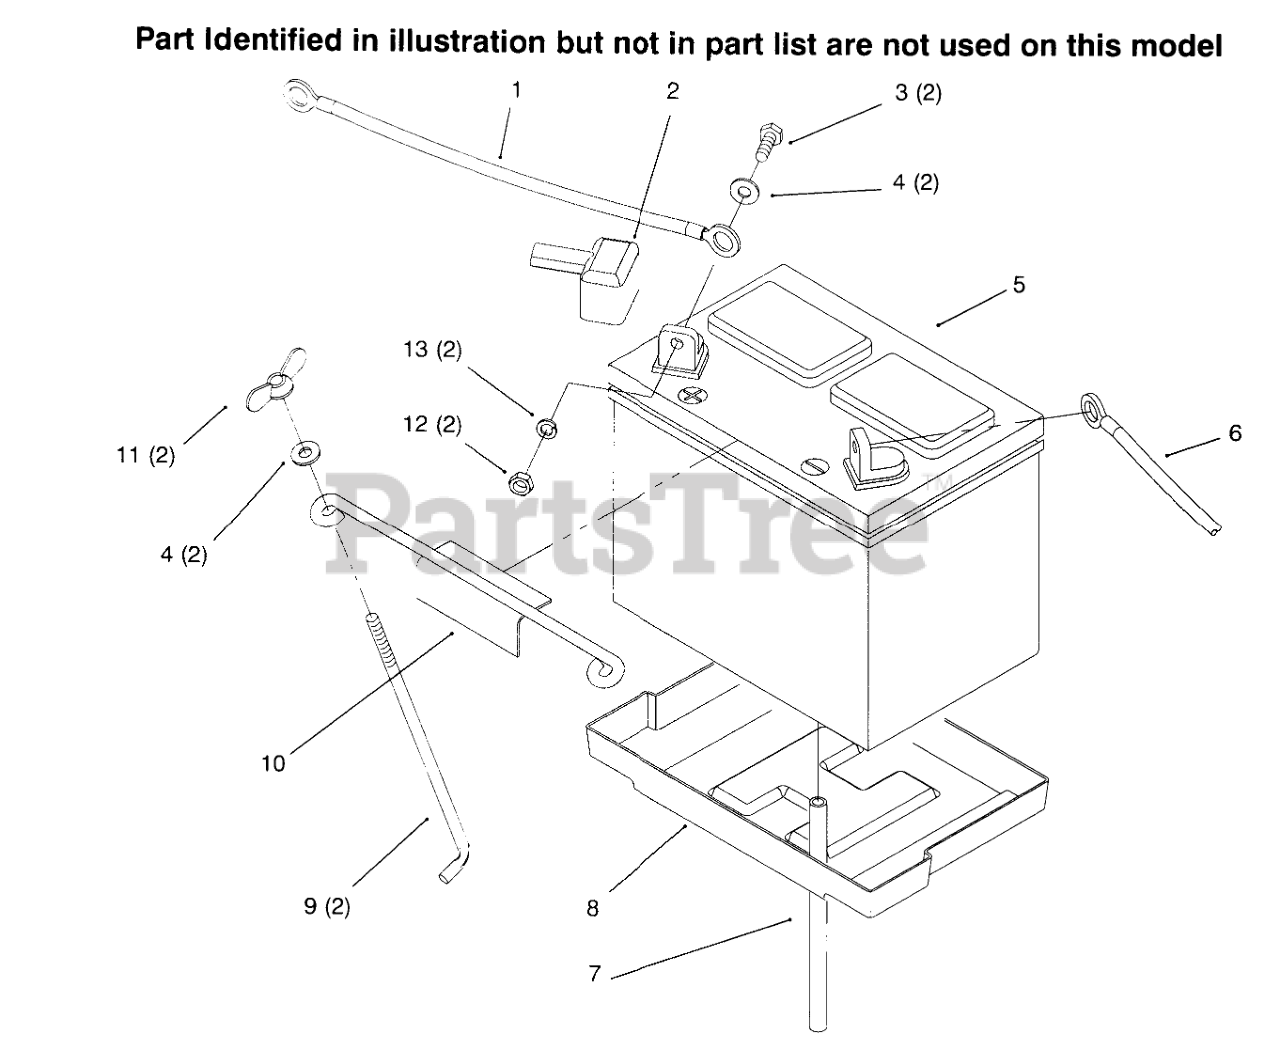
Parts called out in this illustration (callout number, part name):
1	CABLE-BLACK
2	Boot
3	SCREW-HH
4	WASHER-FLAT
5	Battery
6	ASSY WIRE
7	TUBE-21" BATTERY DRAIN
8	TRAY-BATTERY
9	HOOK-BATTERY RETAIN
10	HOLDDOWN-BATTERY
11	NUT-WING
12	NUT-LOCK, NI
13	WASHER-LOCK
